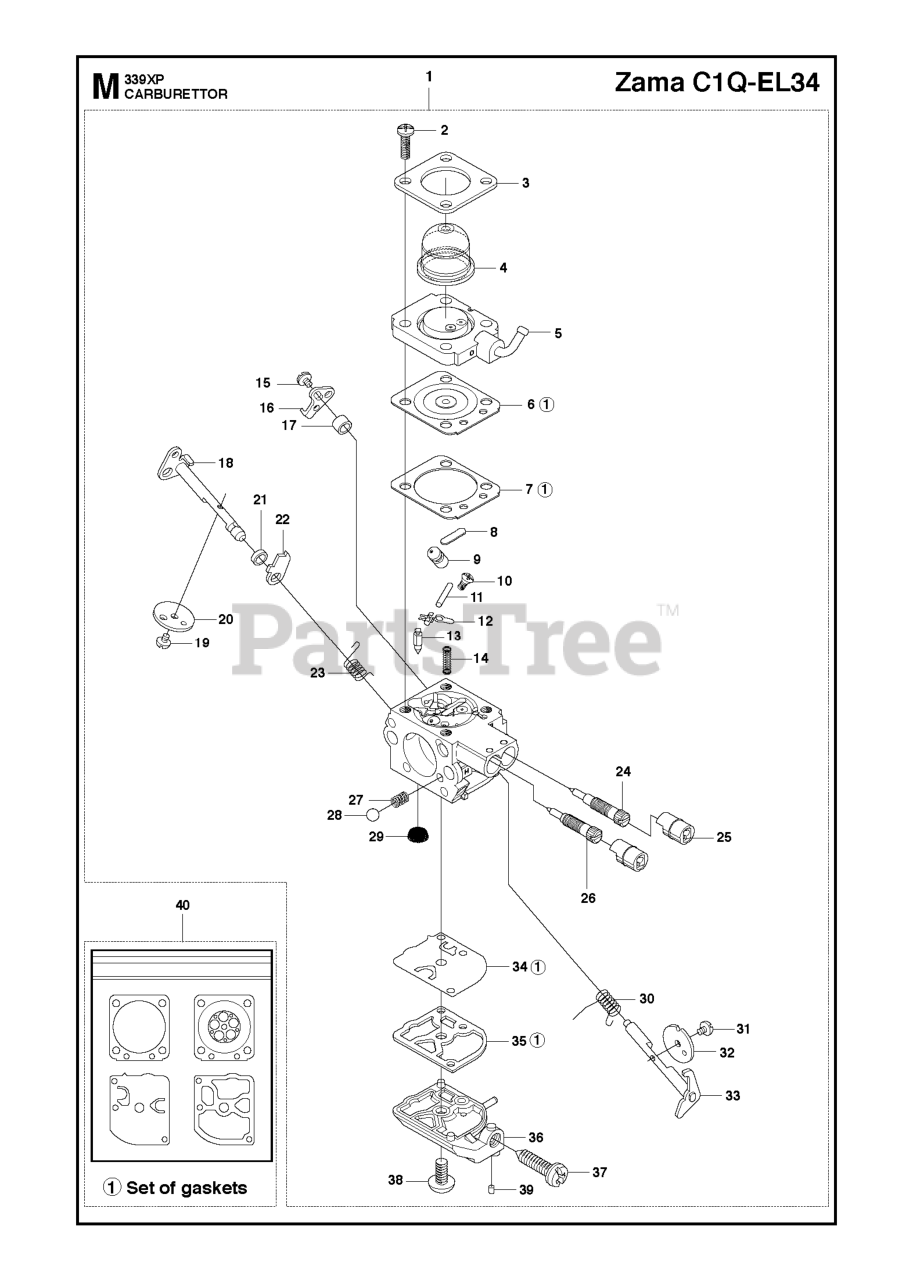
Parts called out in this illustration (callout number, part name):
1	CARBURETOR
11	PIN RETAINING SCREW
13	INLET NEEDLE
24	IDLE SCREW
25	LIMITER CAP KIT
30	SPRING THROTTLE
32	THROTTLE FLAP
34	PUMP DIAPHRAGM
40	GASKET SET
